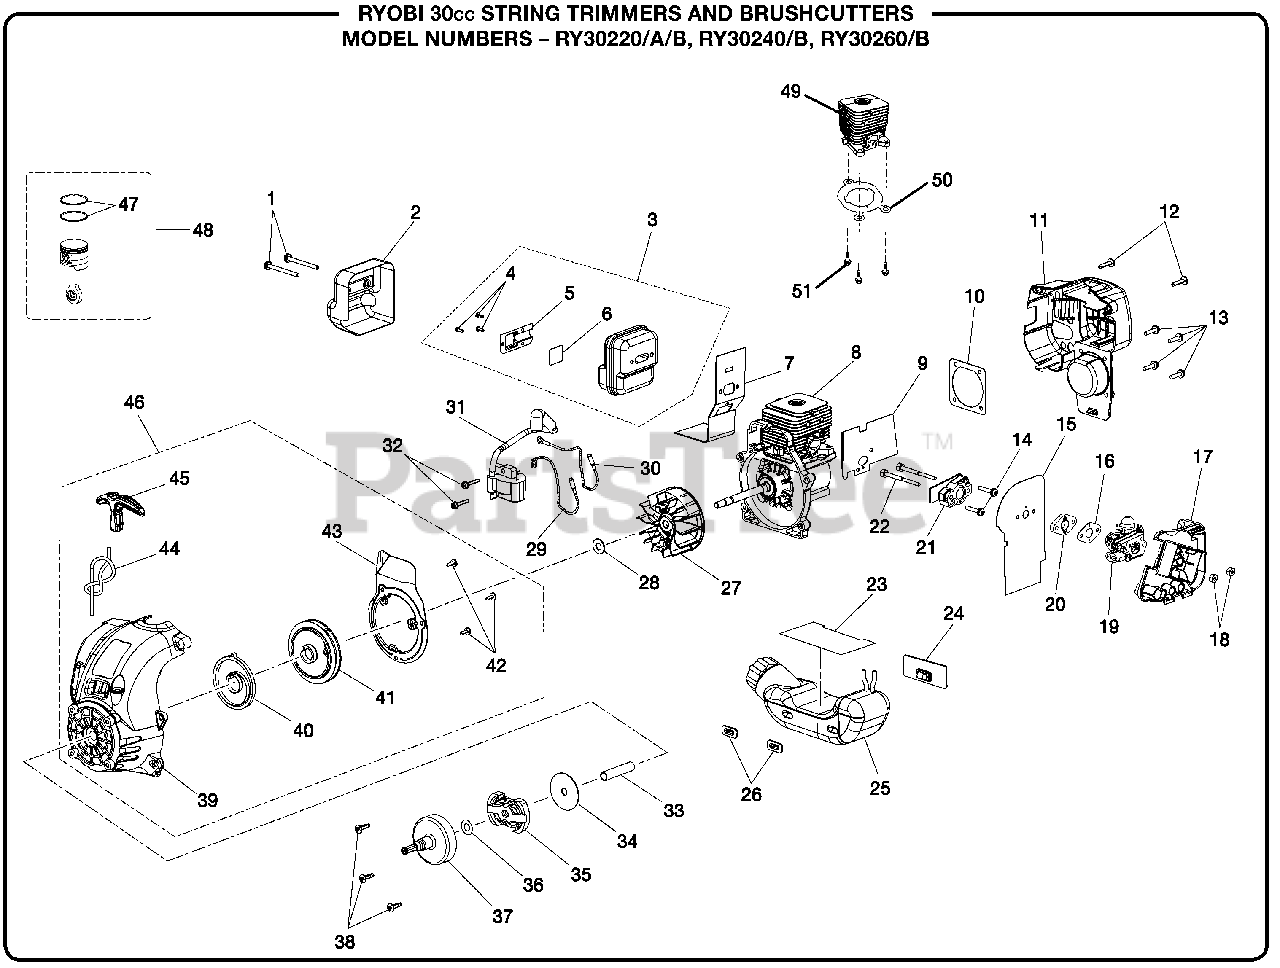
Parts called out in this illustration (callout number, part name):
1	SCREW (10-24 X 2-1/8 in. TORX TR. HD.)
2	HEAT SHIELD
3	MUFFLER ASSEMBLY
4	SCREW (RECESSED PAN HD.)
5	OUTLET TUBE
6	SCREEN
7	MUFFLER GASKET
8	SHORT BLOCK ASSEMBLY (30 cc)
9	INTAKE GASKET
10	COVER GASKET
11	REAR HOUSING
12	SCREW (10-14 X 7/8 in. TRUSS HD. T.F.)
13	SCREW W/LOCK WASHER (10-24 X 3/4 in. PAN HD. TORX)
14	SCREW (PAN HD.)
15	CARBURETOR GASKET
16	CARBURETOR GASKET (NON-STRATO)
17	AIR FILTER BASE
18	LOCK NUT (10-24)
19	CARBURETOR ASSEMBLY
20	SPACER
22	CARBURETOR MOUNTING BOLT (#10 X 2-1/2 in.)
23	TANK INSULATION GASKET
24	RUBBER BUMPER
25	FUEL TANK ASSEMBLY W/CAP
26	BUMPER
27	ROTOR W/PAWLS ASSEMBLY
28	WASHER
29	LEAD W/TERMINALS
30	LEAD W/TERMINALS
31	IGNITION MODULE W/3 SEC. KILL SWITCH
32	SCREW (THD FORMING)
33	SPACER TUBE
34	WASHER (PKG)
35	CLUTCH ASSEMBLY
36	CLUTCH WASHER
37	DRUM AND CONNECTOR
38	SCREW (10-24 X 3/4 in.)
39	STARTER HOUSING AND EYELET ASSEMBLY
40	SPRING AND CONTAINER
41	STARTER PULLEY ASSEMBLY
42	SCREW (THREAD FORMING)
43	BAFFLE/ISOLATOR
44	STARTER ROPE 42 (PKG)
45	STARTER GRIP
46	STARTER HOUSING ASSEMBLY
47	PISTON RING
48	PISTON W/ROD ASSEMBLY
49	CYLINDER, 30CC
50	CYLINDER GASKET
51	SCREW (M5 X 20 mm)
